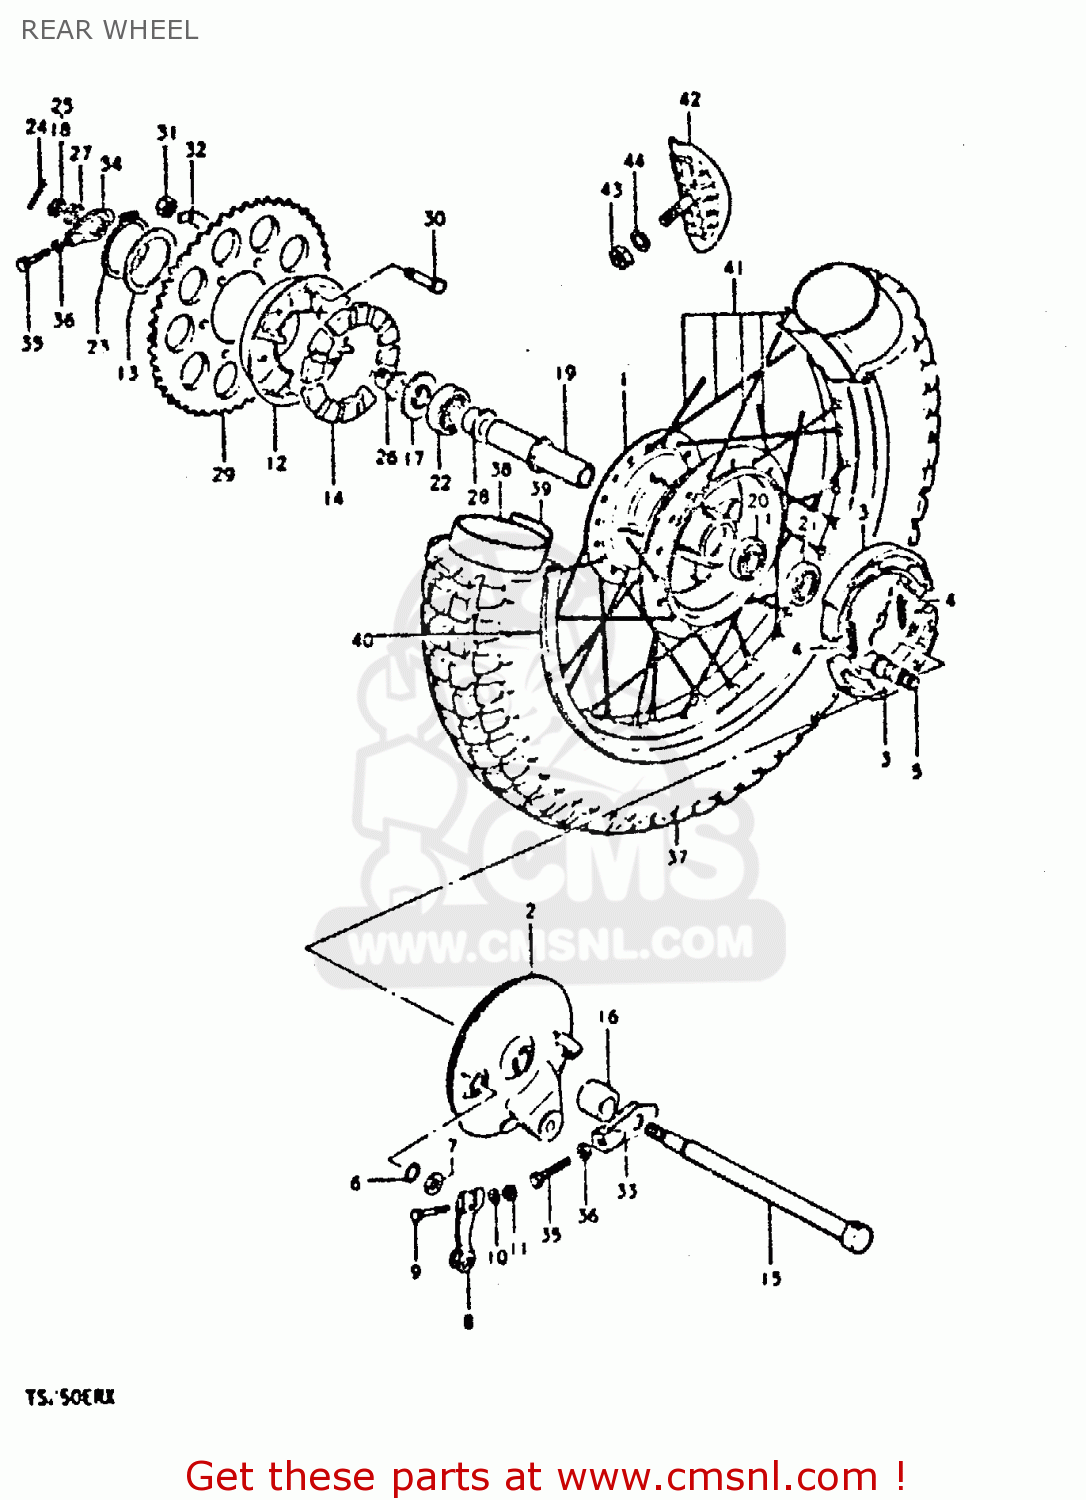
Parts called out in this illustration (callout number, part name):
1	DRUM,REAR HUB
2	PANEL,REAR HUB
3	SHOE,BRAKE (MCA)
4	SPRING
5	CAM,FRONT BRAKE
6	O-RING,BOSS
7	WASHER (15X24X1.6)
8	LEVER,RR BRAKE CAM
9	BOLT 6X40
10	WASHER
11	NUT
12	DRUM,REAR SPROCKET MOUNT
13	WASHER(62.5X77X1.6)
14	ABSORBER,RR WHEEL HUB SHOCK
15	AXLE,REAR
16	SPACER (15.2X26X20)
17	SPACER,REAR AXLE,RIGHT
18	NUT
19	SPACER,REAR HUB BEARING
20	BEARING, RH
21	OIL SEAL
22	BEARING
23	CIRCLIP
24	PIN 30X40
26	SPACER,REAR AXLE,LEFT
27	NUT
28	SPACER,REAR HUB BEARING
29	SPROCKET,REAR
30	BOLT(8X33.5)
31	NUT
32	WASHER
33	ADJUSTER,CHAIN,R
34	ADJUSTER,CHAIN,L
35	BOLT
36	NUT
37	TIRE
38	TUBE,INNER
39	PROTECTOR,WHEEL,INNER
40	RIM,REAR WHEEL (2.15X18)
41	SPOKE SET,RR
42	STOPPER,BEAD
43	NUT
44	WASHER
